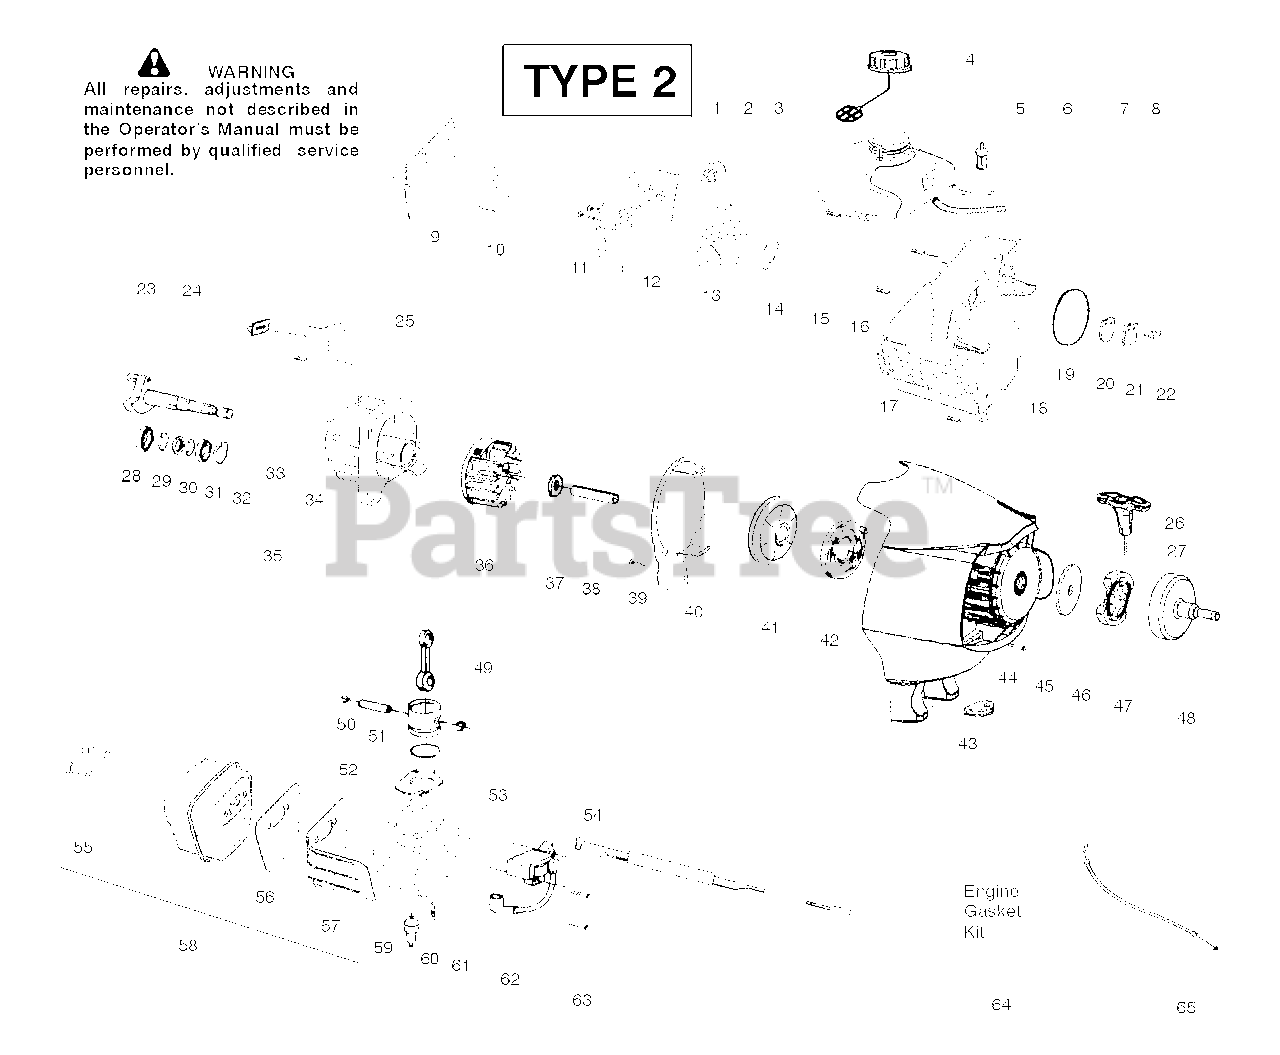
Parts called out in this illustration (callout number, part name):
1	Bulb-Purge
2	Kit-Choke Lever
3	Screw-tank
4	Cap-Fuel w/ret.
5	Assy-Fuel pickup
6	Kit-Fuel line
7	Kit-Fuel/Purge line
9	Cover-Air box
10	Filter-Air
11	Screw-Carb.
13	Kit-Carb assy.
14	Seal-Carb.
15	Assy-Fuel Tank
16	Screw-Crankcase
17	Screw-Shroud
18	Assy-Rear Shroud
19	O-ring-Shroud
20	Valve-Reed
21	Stop-Reed
22	Screw-Reed stop
23	Screw-Retainer
24	Isolator-Tank
25	Ret.-Tank
26	Handle-Starter
27	Kit-Rope
28	Bearing-Inner
29	Retainer
31	Bearing-Outer
32	Ret.-Crankshaft
33	Assy-Crankshaft
34	Assy-Crankcase
35	Assy-C'case/C'shaft
36	Assy-Flywheel
39	Screw-Baffle
40	Plate-Baffle
41	Kit-Pulley
42	Spring-Starter
44	Screw-F/hsg.
45	Assy-Fan Housing
46	Washer-Clutch
47	Assy-Clutch
48	Assy-Drum/Adapter
49	Assy-Conn. Rod
50	Ret.-Piston pin
51	Ring-Piston
52	Kit-Piston
53	Gasket-Cylinder
54	Assy-Leadwire
55	Bolt-Muffler 1/4"-20
56	Gasket-Muffler
58	Kit-Muffler
59	Cylinder
60	Plug-Spark
61	Bolt-Cyl. 1/4"-20
62	Module-Ignition
63	Screw-Module
64	Kit-Gasket/Seal
65	Assy-Throttle cable
